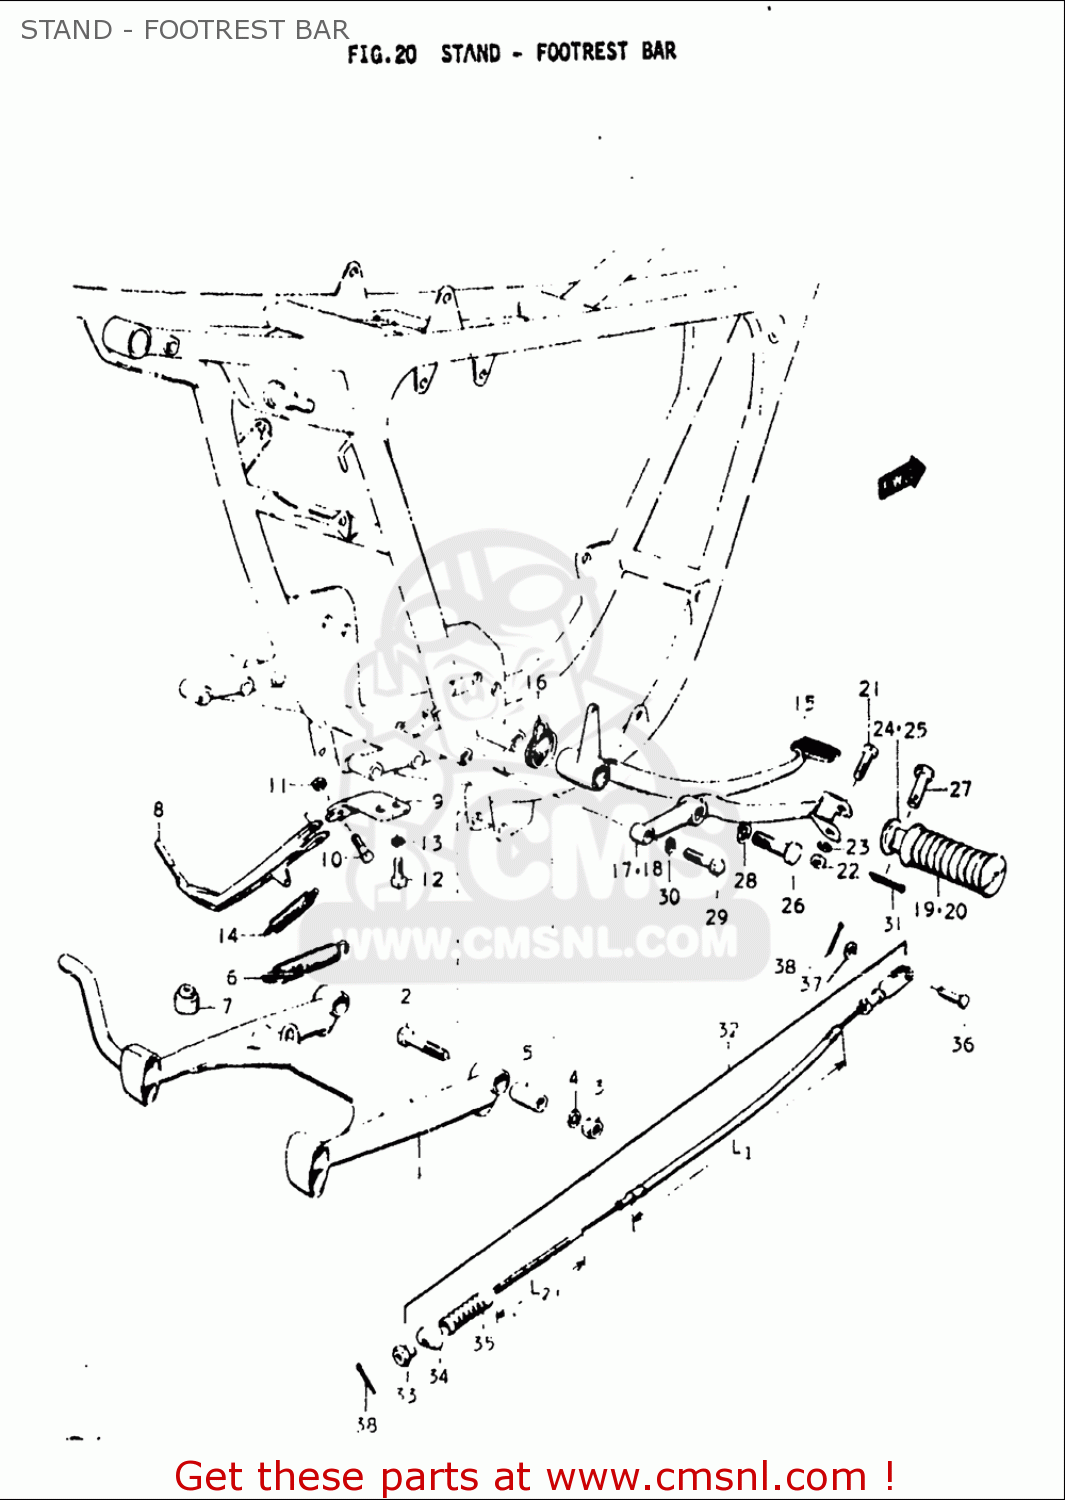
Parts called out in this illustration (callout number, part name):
2	BOLT(10X48)
3	NUT
4	WASHER,LOCK
5	SPACER(10.5X16X30)
6	SPRING
7	CUSHION
10	BOLT(10X27)
11	NUT
12	BOLT
13	WASHER,LOCK
14	SPRING
16	SPRING
20	RUBBER,PILLION FOOTREST
22	NUT
23	WASHER
24	WASHER(22.5X38X1)
25	WASHER(19.5X32X2)
26	BOLT
27	PIN
28	WASHER,LOCK
30	WASHER,LOCK
33	NUT
34	PIN(13X18)
35	SEAL,DUST
36	PIN(L:17.5)
37	WASHER
38	PIN
